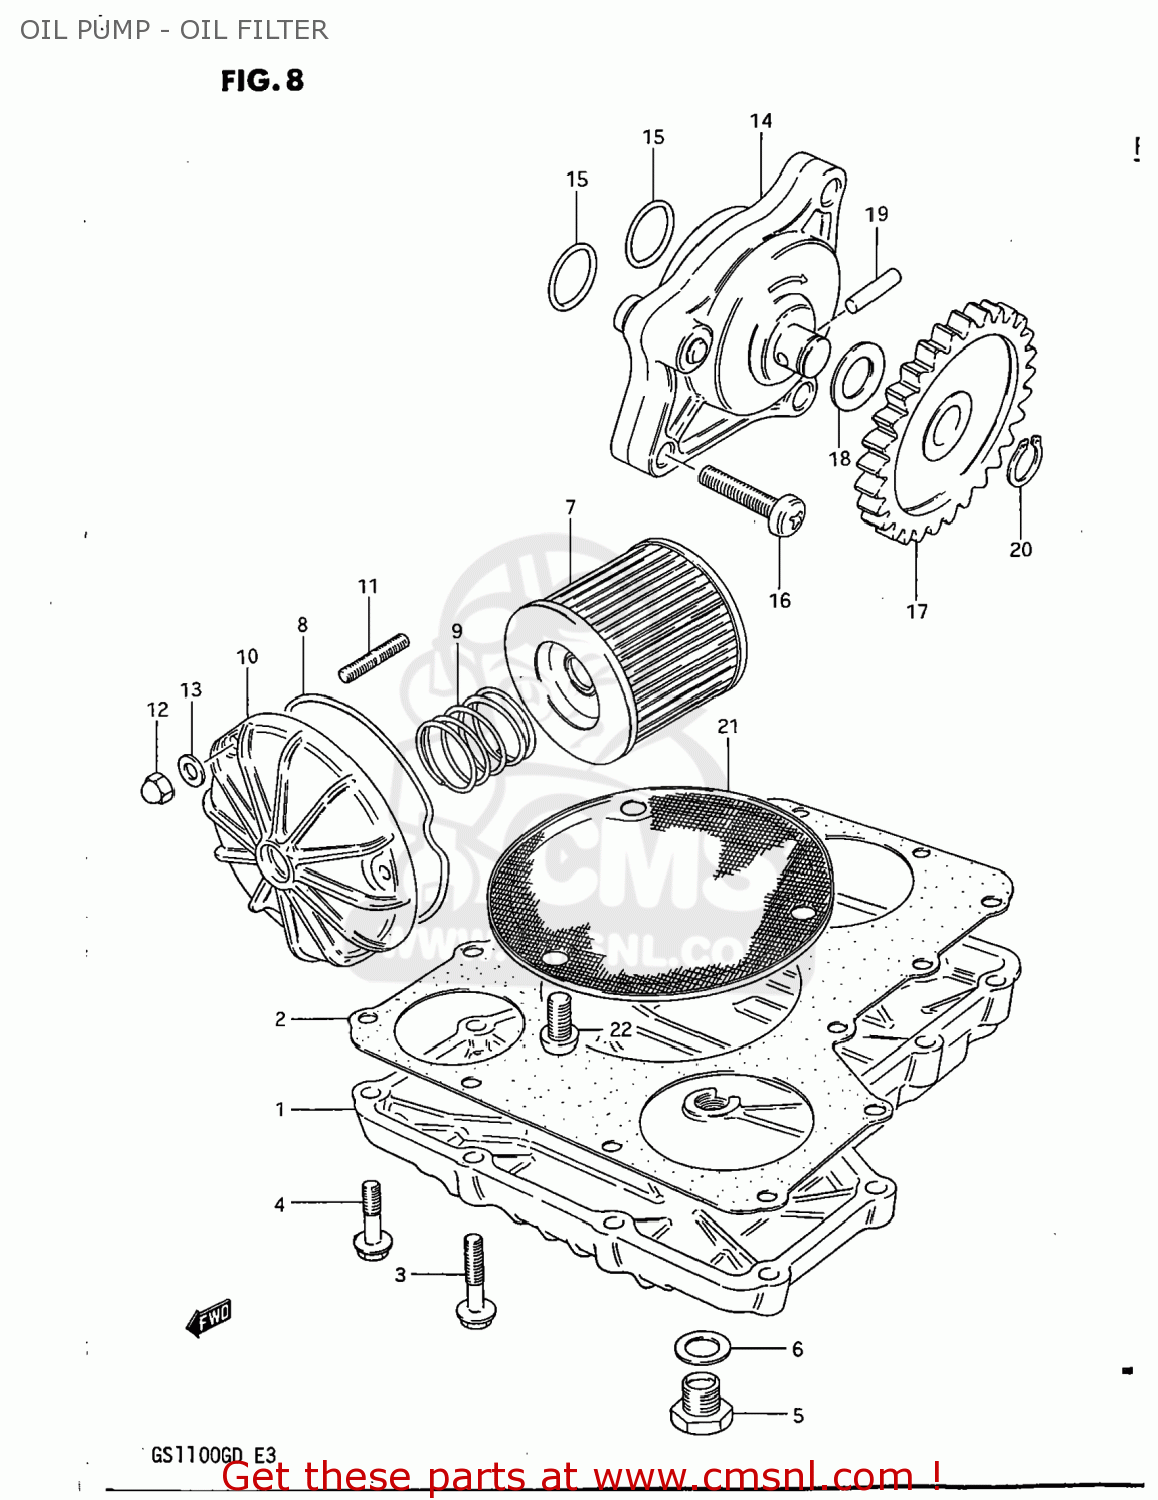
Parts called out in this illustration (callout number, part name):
1	PAN,OIL
2	GASKET,OIL PAN (MCA)
3	BOLT
4	BOLT
5	PLUG
6	GASKET(14X19.2X2) (NAS)
7	FILTER ASSY,ENGINE OIL
8	O RING,OIL FILTER CHAMBER CAP
9	SPRING
10	CAP,OIL FILTER
11	STUD 6X20
12	NUT
13	WASHER
14	PUMP ASSEMBLY,ENGINE OIL
15	O RING(D:1.9,ID:13)
16	SCREW
17	GEAR,ENG OIL PUMP DRIVEN(NT:33
18	SHIM
19	PIN(4X15.8)
20	CIRCLIP
21	STRAINER,ENGINE OIL
22	SCREW 6X12
